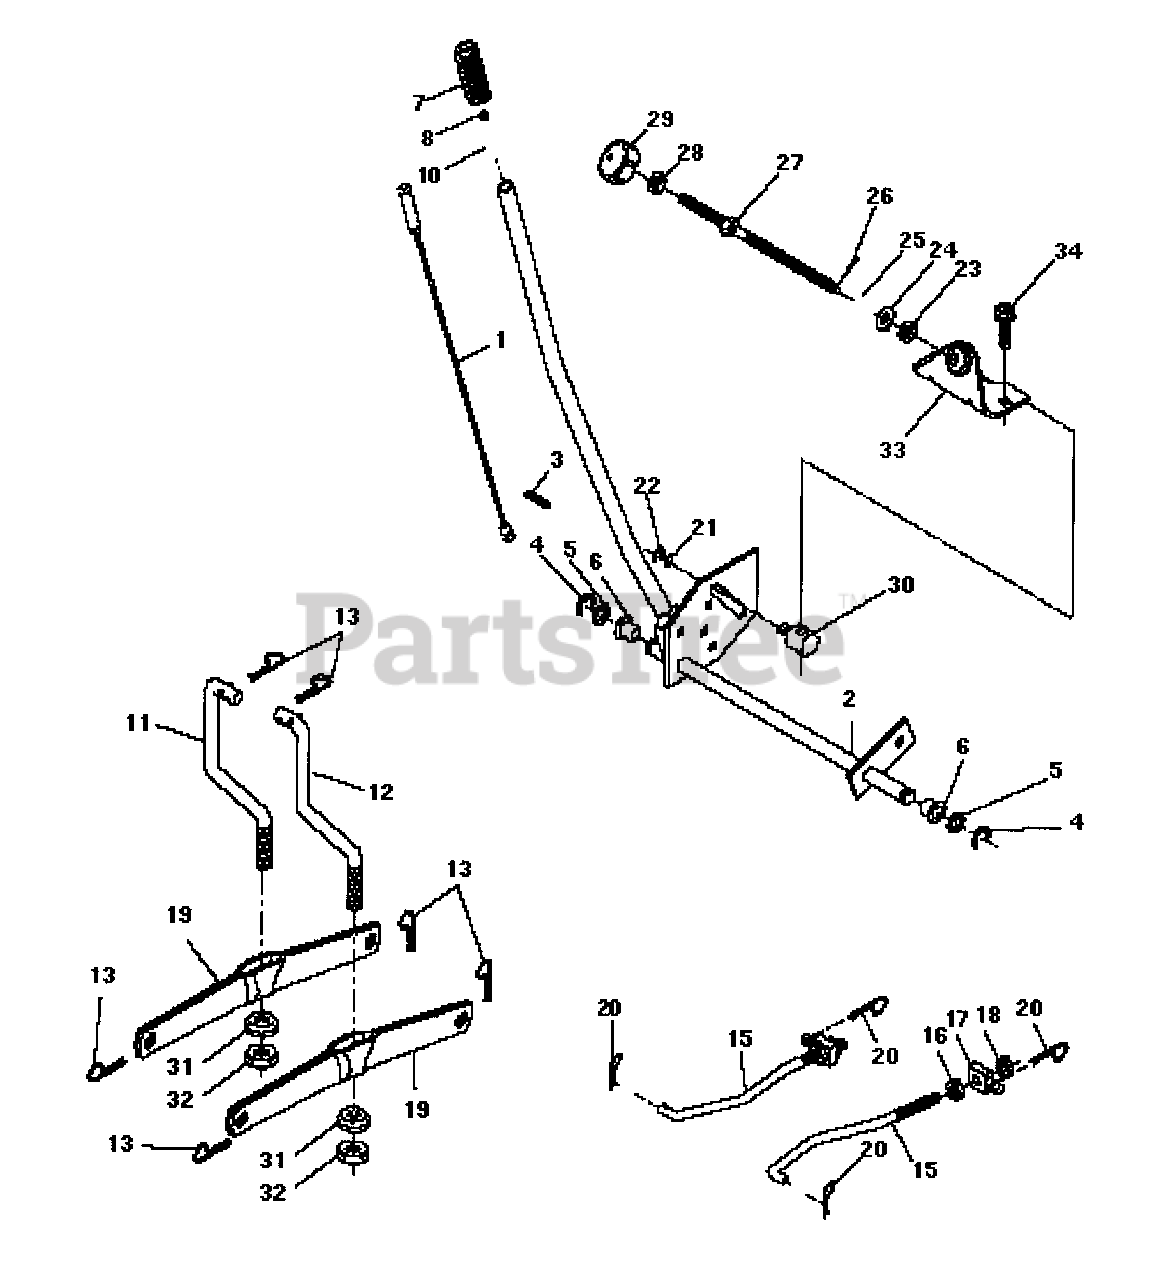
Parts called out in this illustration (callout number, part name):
1	Wire Asm Inner w/plunger
2	Shaft Asm Lift LH Inf Hgt P/L
3	Pin Groove
4	E Ring #5133-62
5	Washer PLTD 21/32 X 1 X 21ga
6	Bearing Nylon Blk 629 Id
7	Grip Handle Bicycle Matte Blk
8	Button Plunger Black
10	Spring Cprsn 3 750 Oiled
11	Link Lift LH
12	Link Lift RH
13	Retainer Spring
15	Link Front
16	Nut Jam Hex 1/2-13 Unc
17	Trunnion Blk Zinc
18	Nut Lock W/wsh 1/2-13unc
19	Arm Suspension Rear
20	Retainer Spring
21	Washer 15/32 X 3/4 X 16ga
23	Nut Special
24	Washer 13/32 x 5/8 x 16 ga
25	Spring 2-1/8
26	Pin Cotter 3/32 x 1/2
27	Rod Adj Lift
28	Nut Hex Jam 3/8-16 Unc
29	Knob Inf 3/8-16 UNC
30	Trunnion Dp Stop
31	Bearing Pivot Lift Spherical
32	Nut Crownlock 3/8-24
33	Bracket Stop Inf Hgt
34	Screw Thdrol 3/8-16 x 1/2
